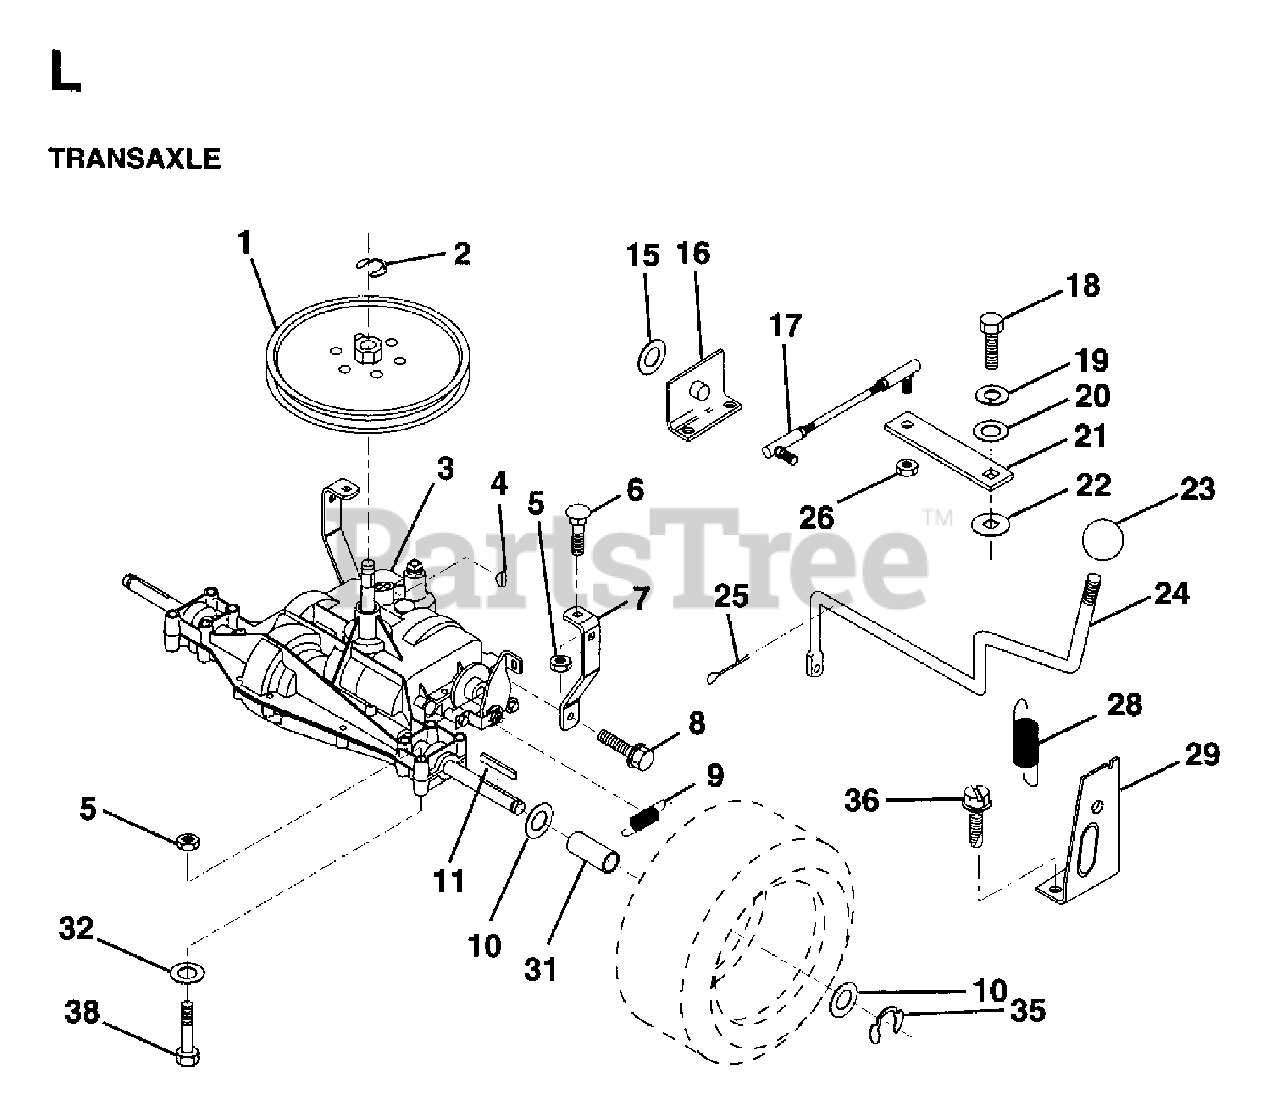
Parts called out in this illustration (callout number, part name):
2	RETAINING RING LT
5	LOCKNUT
6	BOLT
7	STRAP,TORQUE
8	SCREW
9	SPRING,BRAKE RETURN
11	SQUARE KEY
15	WASHER
16	SUPT, HDLE SHT LH
18	BOLT 1/4-28X3/4
19	LOCKWASHER
20	WASHER LT
22	WASH-SHFT PLT LT
23	KNOB.DUCKHEAD.1/2
24	ROD, SHIFT
25	PIN COTTER
26	LOCKNUT
28	SPRING.EXTENSION
29	SUPPORT HANDLE SHAFT RH
31	SPACER AXLE
32	WASHER
36	SCREW
38	BOLT HEX 5/16-18 GR 5
